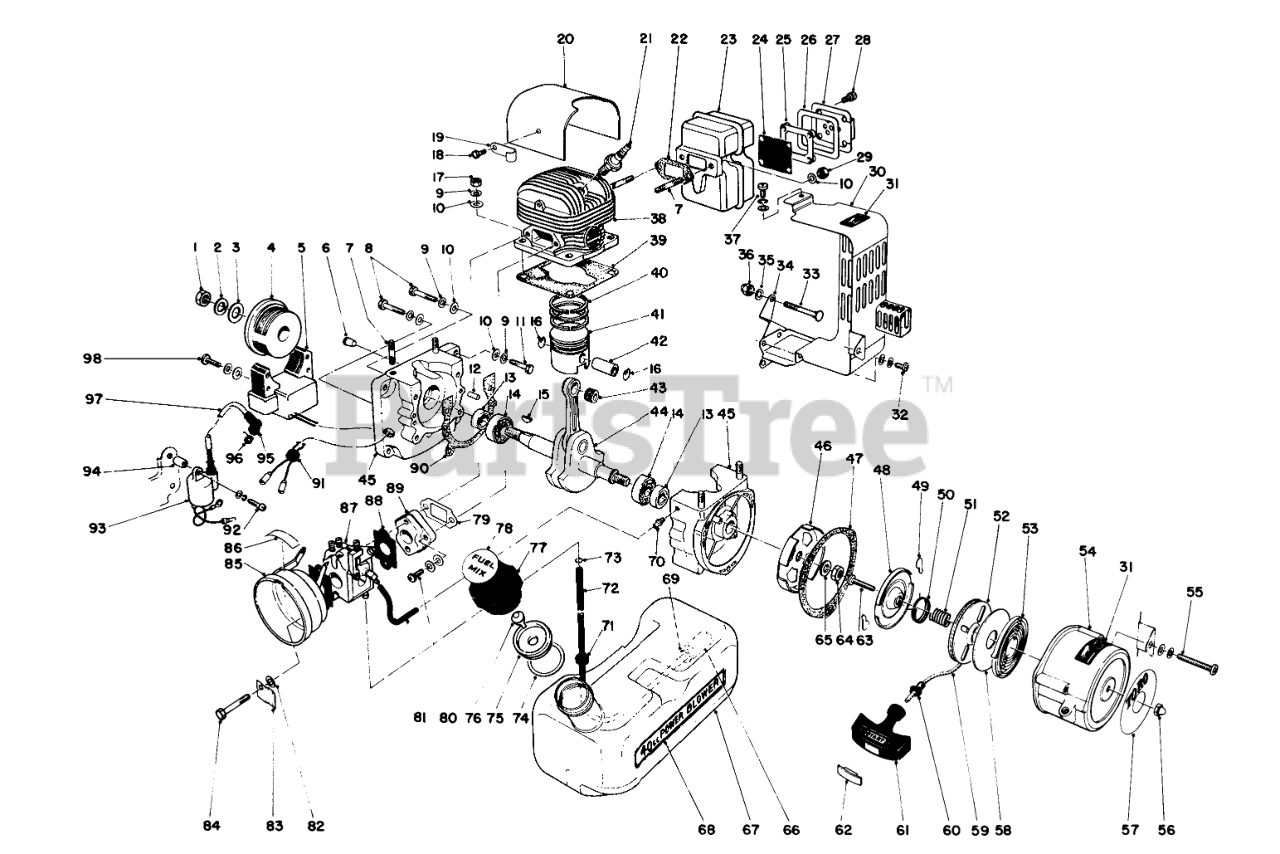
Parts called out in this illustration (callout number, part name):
2	Spring Washer
3	Washer
4	Rotor
5	C.D.I. MODULE - ECHO
9	Washer
10	Washer
12	Knockpin
13	Oil Seal
14	Ball Bearing
15	Woodruff Key
16	CIRCLIP PISTON PIN
19	Clamp
20	Cylinder Cover
21	Spark Plug
22	Gasket Muffler
23	Muffler Assembly (Incl. Ref.#22-30, 35 & 7)
24	Screen
25	Seat Screen
26	Packing Holder
27	Holder Screen
28	Screw
29	LOCKNUT
30	MUFFLER COVER
31	Decal-Hot Surface
32	SCREW
33	Bolt, Elbow
34	Bracket-Muffler Cover
35	WASHER
36	Capnut
37	SCREW W/WASHER
38	Cylinder
39	Packing Cylinder Base
40	PISTON RING
41	Piston
42	Piston Pin
43	Needle Bearing
44	Crankshaft Assembly
45	Crankcase Set
46	PAWL CATCHER
47	STARTER CASE GASKET
48	FRICTION PLT
49	RATCHET
50	RATCHET SPRING
51	SPRING
52	Recoil Drum
53	REWIND SPRING
54	Starter Case
55	SCREW
56	Cap Nut
57	Decal-Toro
58	Side Plate, Starter
59	Starter Rope
60	Rope Guide
61	Starter Handle
62	Cap, Starter Handle
63	Screw
65	Washer
66	Fuel Strainer
67	Fuel Tank
68	Decal-40cc
69	Washer
70	Connector
71	GROMMET
72	FUEL PIPE
73	Clip Fuel Pipe
74	FUEL TANK GASKET
75	Holder, Check Valve
76	Check Valve
77	FUEL TANK CAP - WILLMAR
78	Decal-Fuel Mix
79	GASKET
80	SCREW
82	Washer
83	Choke Clip/Washer (Incl. Ref. #82)
85	CLEANER CASE-WILLMAR
86	Decal-Caution
87	CARBURATOR ASM
88	GASKET
89	INSULATOR
90	Packing, Crankcase
91	Grommet
92	Screw
94	Spacer
95	Cap-Spark Plug
96	Coil Spring-Plug Cap
97	Sleeve
